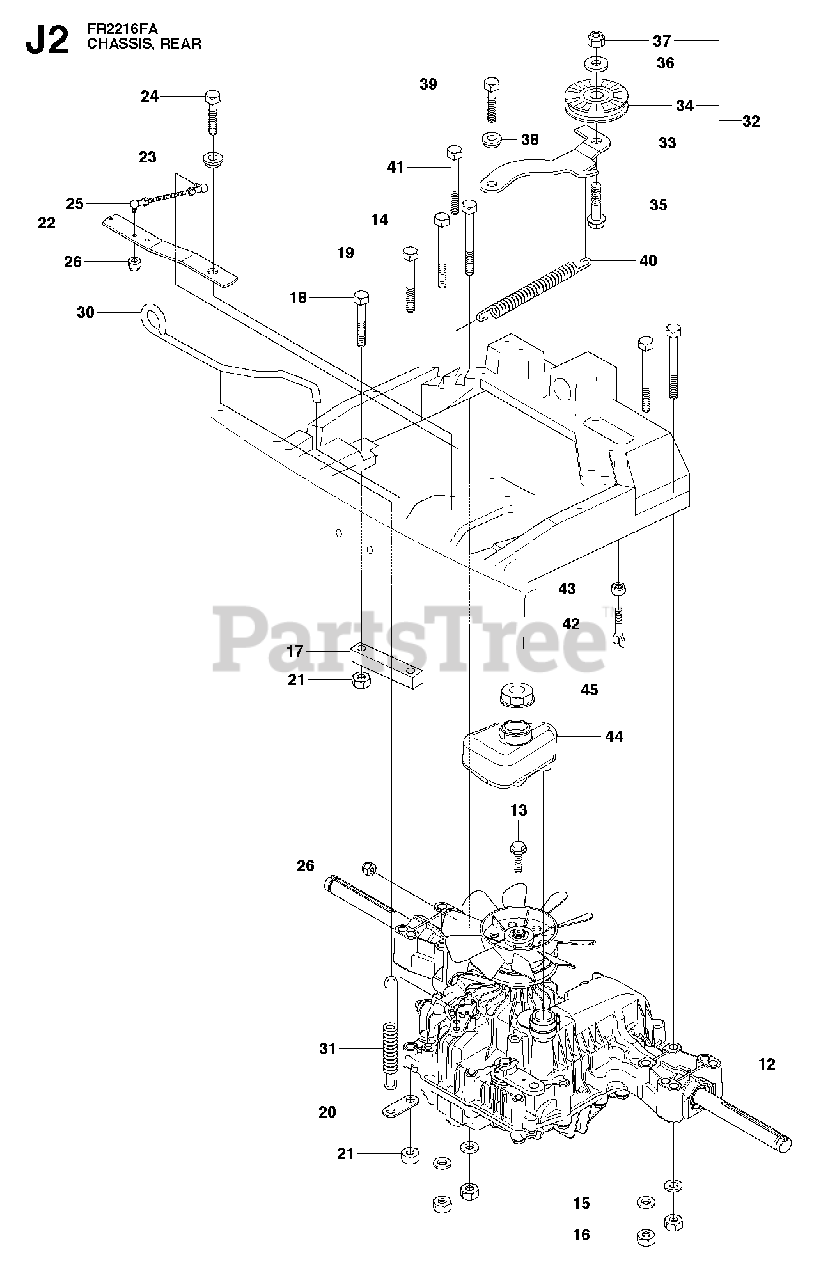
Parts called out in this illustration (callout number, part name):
12	HYDROSTAT
15	WASHER BRB 8.4X17
16	NUT
20	CONNECTOR
21	NUT
23	WASHER
24	SCREW 8X20
26	LOCKNUT M5
31	SPRING
32	TENSIONER
33	TENSIONER
34	PULLEY
35	SCREW
36	SPACER
37	LOCKNUT M8
38	WASHER
39	SCREW 8X20
